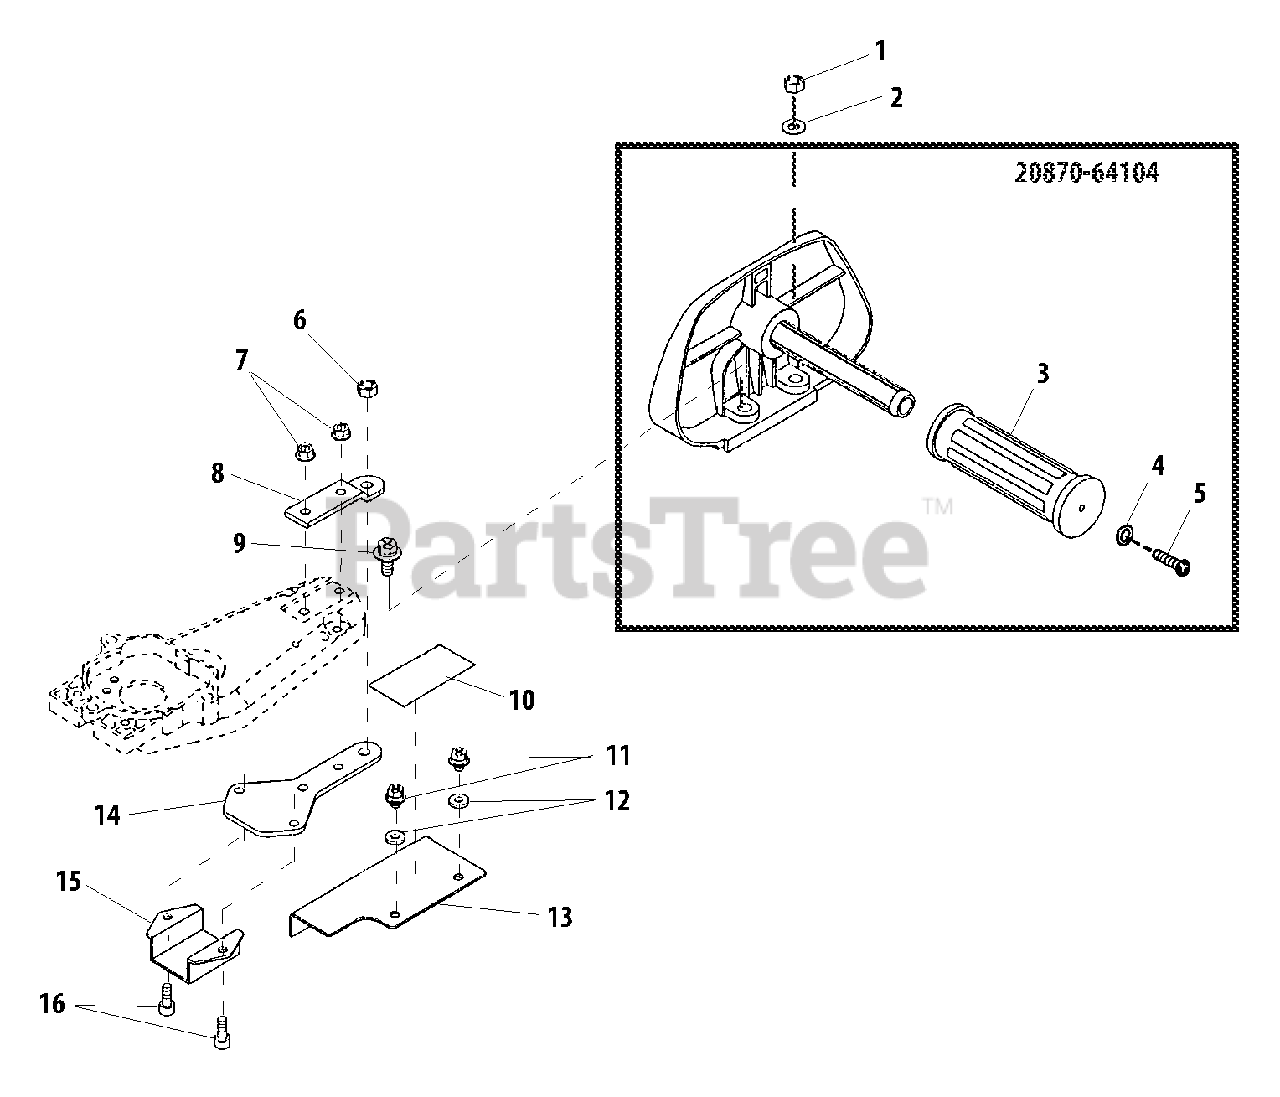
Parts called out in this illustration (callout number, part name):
1	NUT M6
2	WASHER 6.5×13×1
3	GRIP
4	WASHER 5 MM
5	SCREW 5×20
6	NUT M6
7	NUT, FLANGE M5
8	HOLDER
9	NUT, FLANGE M5
10	LABEL, WARNING
11	BOLT M5×8
12	WASHER 5
13	PROTECTOR
14	PLATE
15	BRACKET
16	BOLT 5×12
20870-64104	HANDLE ASSY, FRONT
